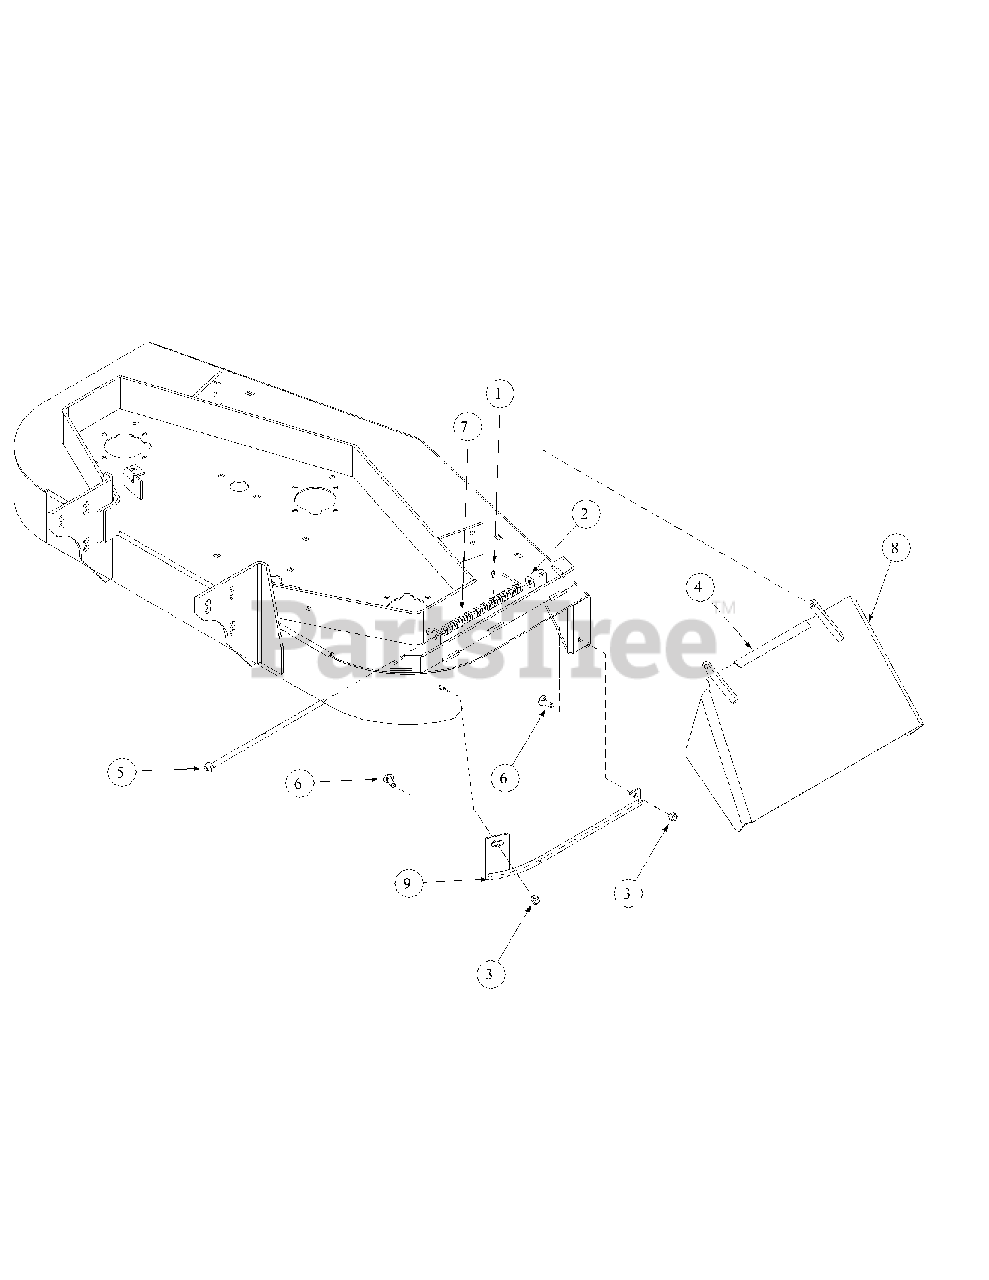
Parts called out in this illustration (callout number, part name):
1	Cotter Pin, 5/32 x 1" Lg. Zinc
2	Flat Washer, 3/8 Zinc
3	Lock Nut, Nylon Insert, 3/8-16
4	Decal, Cut LIne
5	Pin Deflector Assembly, Weldment
6	Carriage Bolt, 3/8-16 x 2
7	Torsion Spring
8	Chute Assembly
9	Stiffner Assembly, 48
